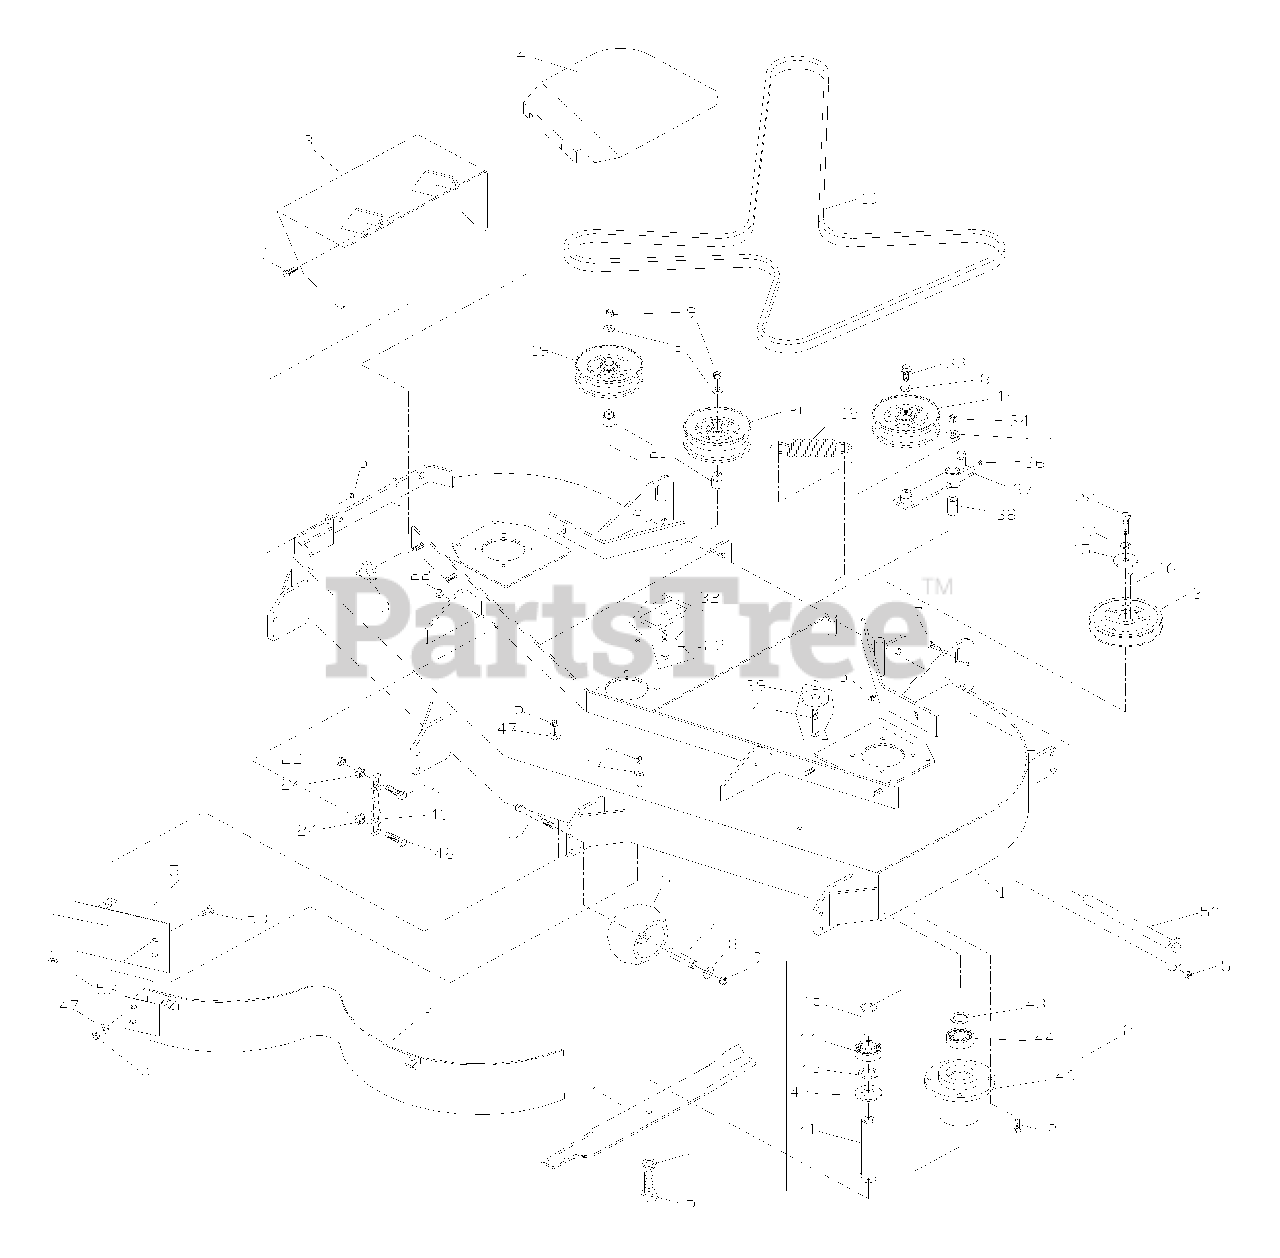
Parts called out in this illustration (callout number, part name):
1	DECK W/DECALS
2	CUTTER HOUSING ASM.
5	NUT 5/16 LOCK
8	3/8 FLAT WASHER
9	NUT 3/8 LOCK
10	BELT
11	HCS 3/8 X 3.5
12	HCS 5/16 X 1.00
13	DISCHARGE CHUTE
14	BELT SHIELD RT.
14	BELT SHIELD LT.
16	KEY 1/4 SQ.
17	HCS 5/16 X .750
19	PULLEY 1.31
20	PULLEY 1.62
21	IDLER BUSHING
22	NUT 7/16 LOCK
23	HCS 3/8 X 2.5
24	NUT 7/16 WHIZ
25	HCS 5/8F X 1.25
26	WASHER 5/8 LOCK
27	7/16 LOCK WASHER
28	HCS 7/16F X 1.5
32	PAD
33	HCS 3/8 X 1.0 SERR.
34	NUT 1/2 NYLOC
35	WASHER 1/2 FLAT
36	ZERK
38	PIVOT BUSHING
39	SUPPORT WASHER
40	HCS 1/2 X 3.25
42	MACHINE BUSHING
43	MACHINE BUSHING
44	BEARING
47	5/16 FLAT WASHER
48	HCS 7/16 X 1.5
49	LIFT CHAIN
51	BAFFLE , CENTER
52	BAFFLE, MAIN
53	RHSNB 5/16 X 5/8
